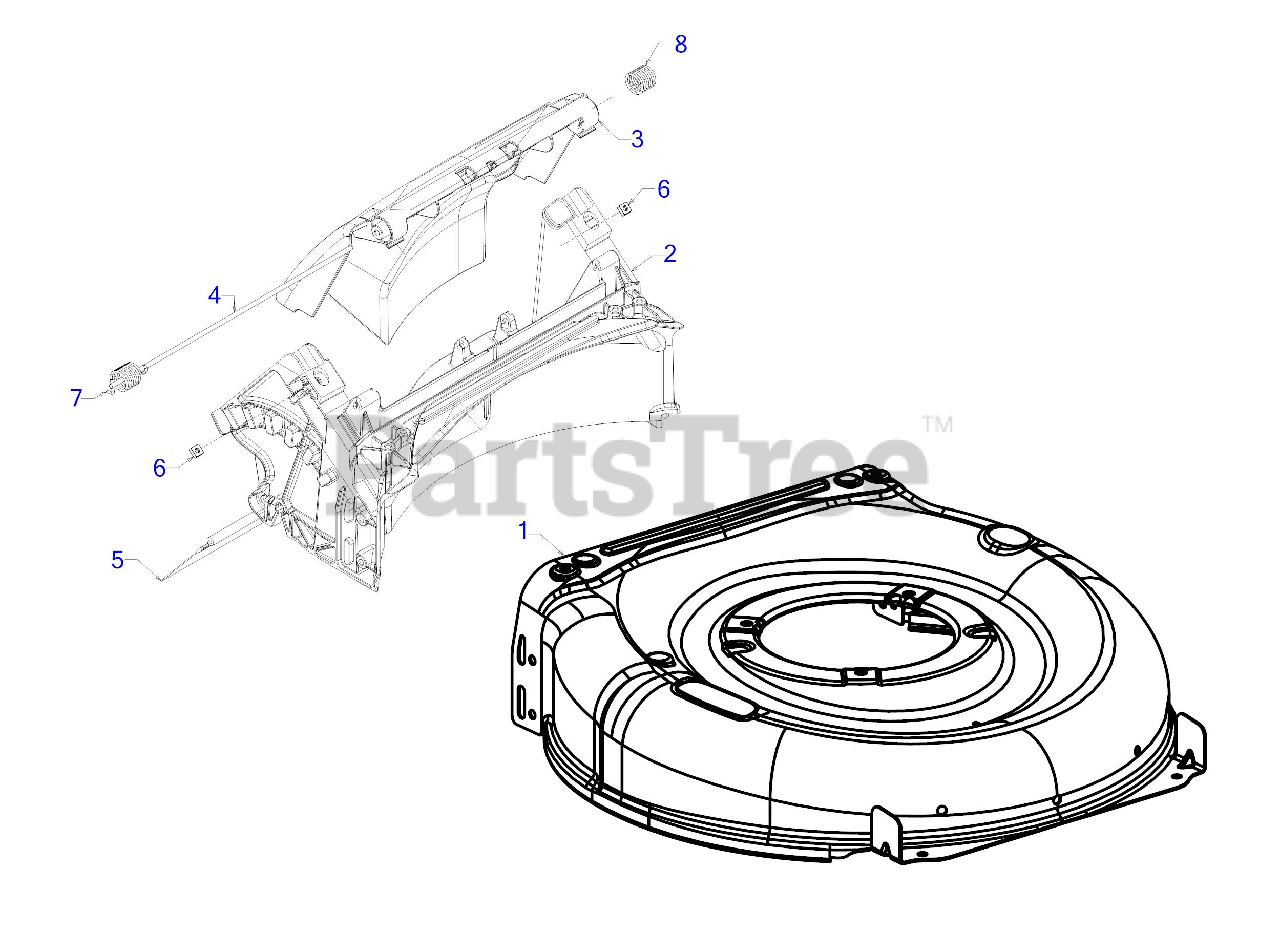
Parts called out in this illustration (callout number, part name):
2	REAR BAG DOOR ASSEMBLY
3	REAR BAG DOOR ASSEMBLY
4	REAR DOOR PIVOT ROD
5	TRAILSHIELD
6	SQUARE NUT 1/4-20
7	TORSION SPRING (RH)
8	TORSION SPRING (LH)
